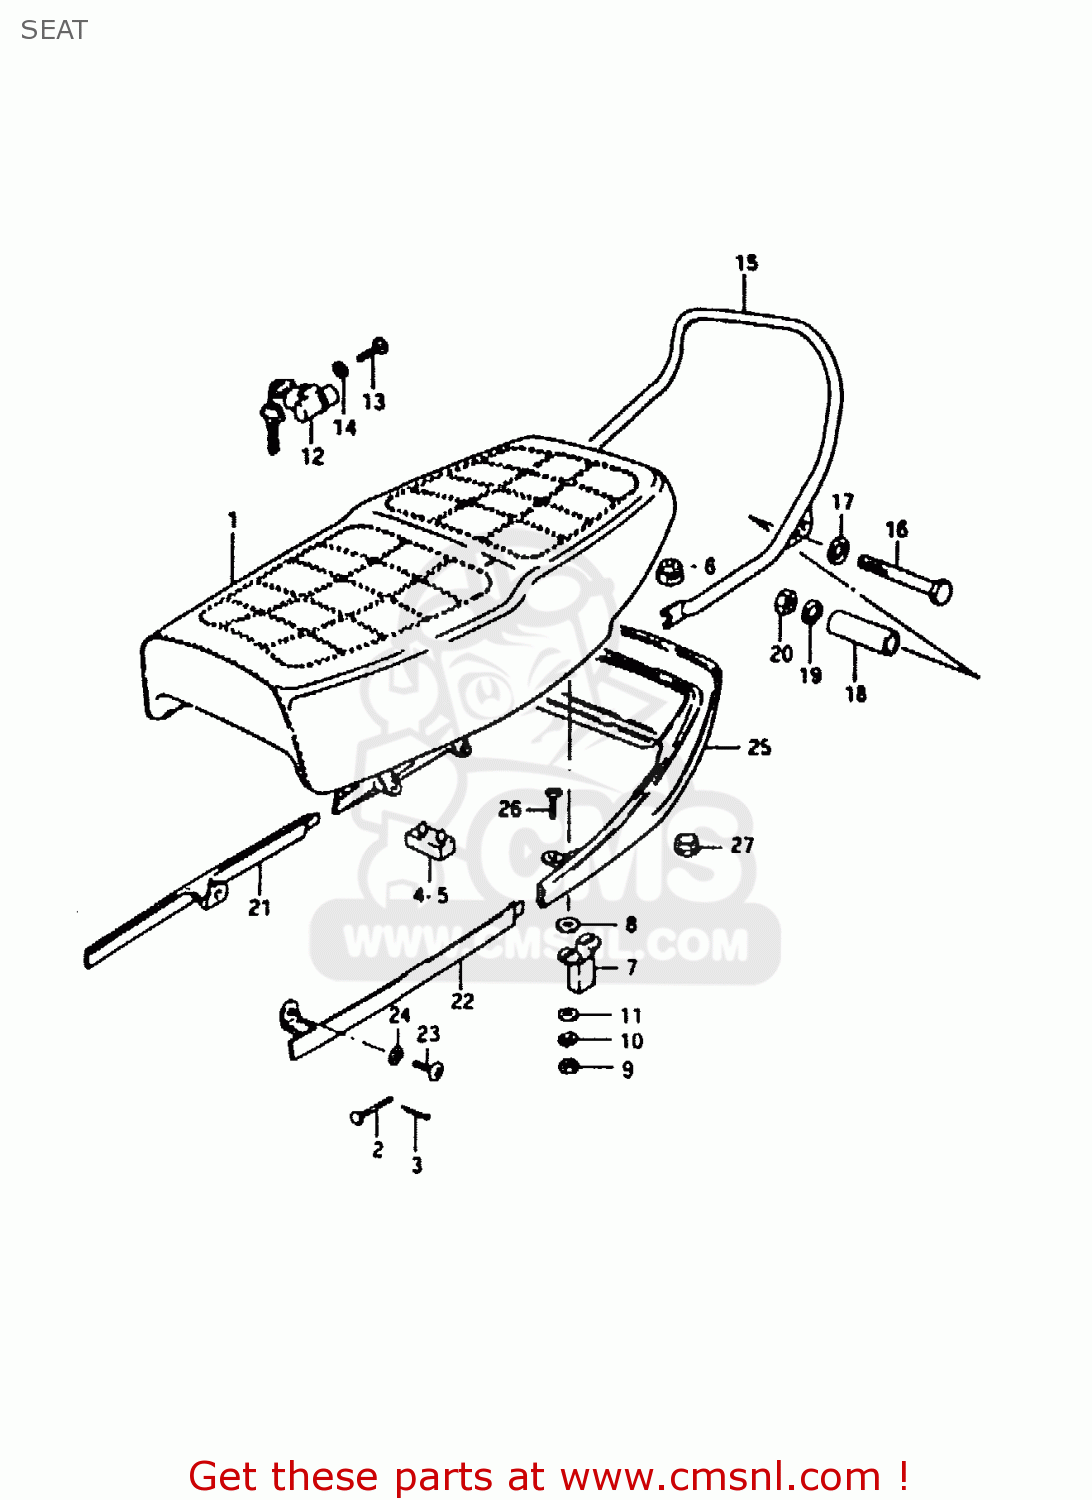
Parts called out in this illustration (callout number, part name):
1	SEAT ASSY
2	PIN
3	PIN
4	CUSHION
5	CUSHION
6	CUSHION(11.5X22X20)
7	PLATE,CLAMP GUIDE
8	WASHER(6.5X18X1)
9	NUT
10	LOCK WASHER
11	WASHER
12	LOCK ASSY,SEAT
13	SCREW
14	LOCK WASHER
15	BAR, PILLION RIDER
16	BOLT 10X65
17	WASHER
18	SPACER
19	LOCK WASHER
20	NUT
21	PLATE, SEAT LOWER RH
22	PLATE, SEAT LOWER LH
23	SCREW
24	LOCK WASHER
25	TAIL COVER, SEAT
26	SCREW
27	PLUG(OD:19)
